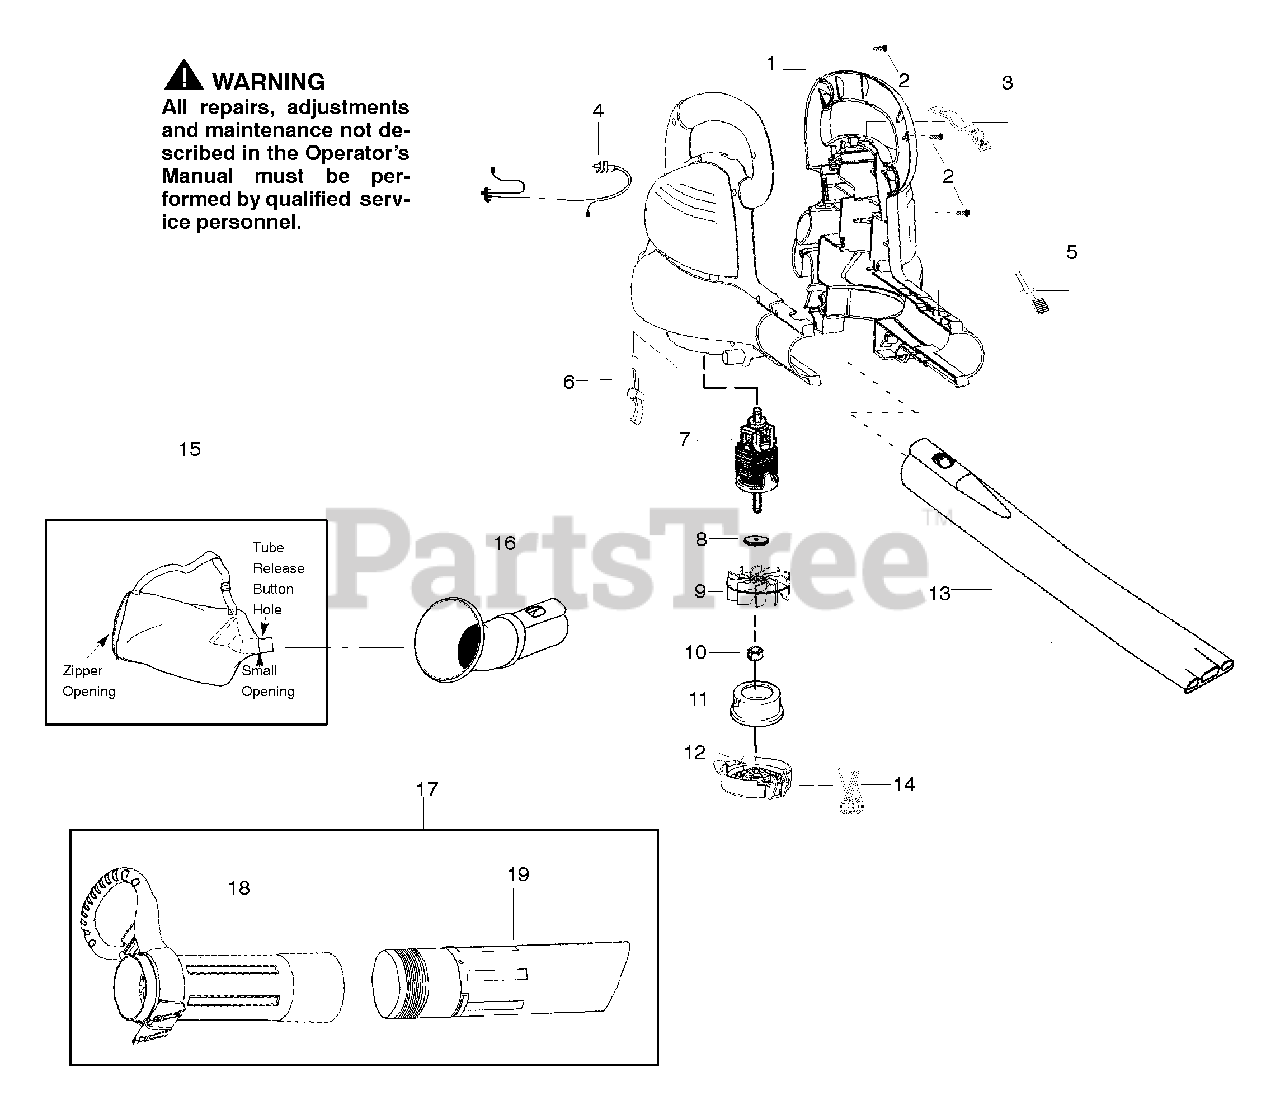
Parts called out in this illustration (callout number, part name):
1	Housing Set
3	Cover - Switch
4	Assy Wiring Harness
5	Button - Tube Latch
6	Button - Door Latch
7	Assy Motor
9	Impeller
10	Nut - Impeller
11	Restrictor - Inlet
12	Door - Vacuum Inlet
13	Tube - Blower
14	Spring - Door
15	Assy - Vac Bag
16	Tube - Elbow
17	Kit-Upper/Lower Tube w/handle
18	Tube - Upper Vac w/handle
19	Tube - Lower Vac
